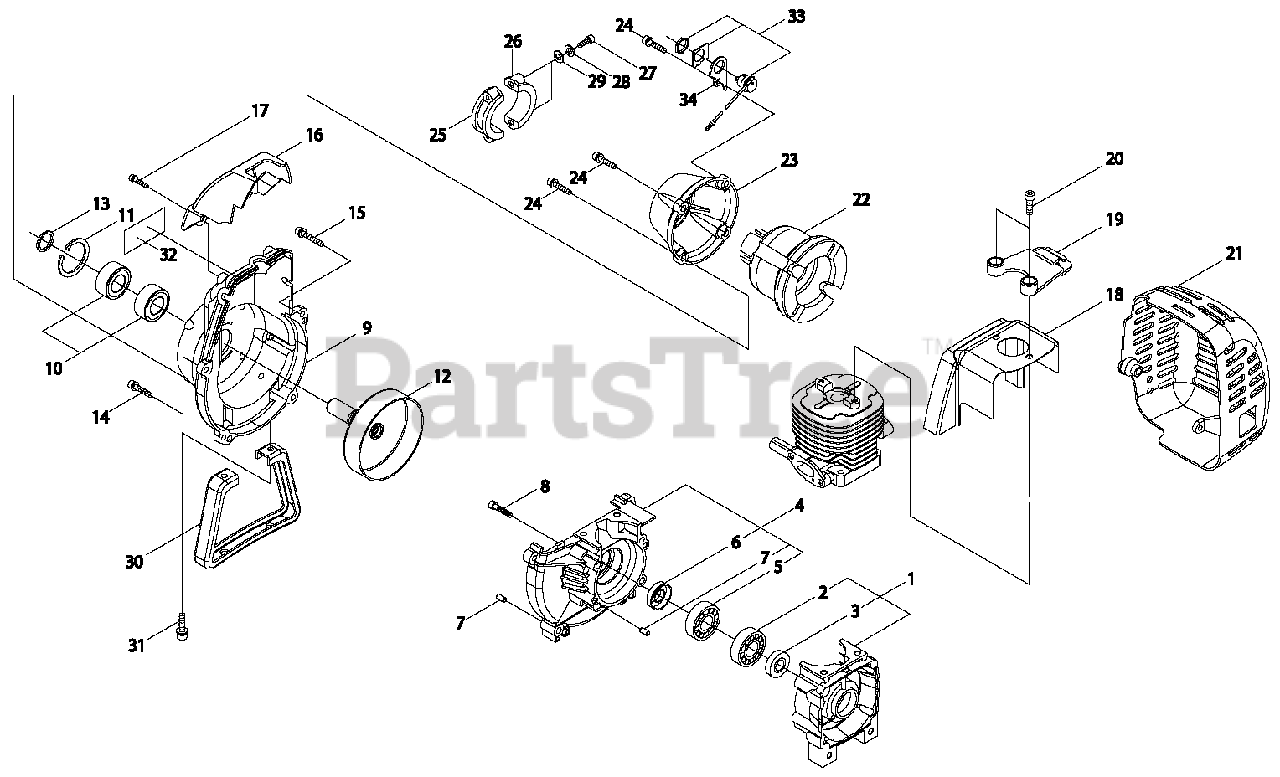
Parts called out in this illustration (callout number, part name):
1	CRANKCASE ASSY, S
2	BEARING, BALL 6202 C3
3	SEAL, OIL 16
4	CRANKCASE ASSY, M
5	BEARING, BALL 6202 C3
6	SEAL, OIL 16
7	PIN, LOCATING 5×10
8	BOLT 5×30
9	COVER, FAN
10	BEARING, BALL 6002 DDU
11	RING, SNAP Ø32
12	DRUM, CLUTCH
13	RING, SNAP
14	BOLT M5×20
15	BOLT M5×30
16	GUARD, TOP
17	BOLT M4×16
18	COVER, ENGINE
19	STAY, ENGINE COVER
20	BOLT M5×18
21	COVER, MUFFLER
22	CUSHION, AV
23	CAP, CUSHION
24	BOLT M5×20
25	CLAMP - A
26	CLAMP - B
27	BOLT 5×25
28	WASHER, SPRING 5
29	WASHER, FLAT 5.5×10×0.8
30	STAND
31	BOLT M5×16
32	LABEL, TRADE
33	SWITCH, ON-OFF
34	BRACKET
